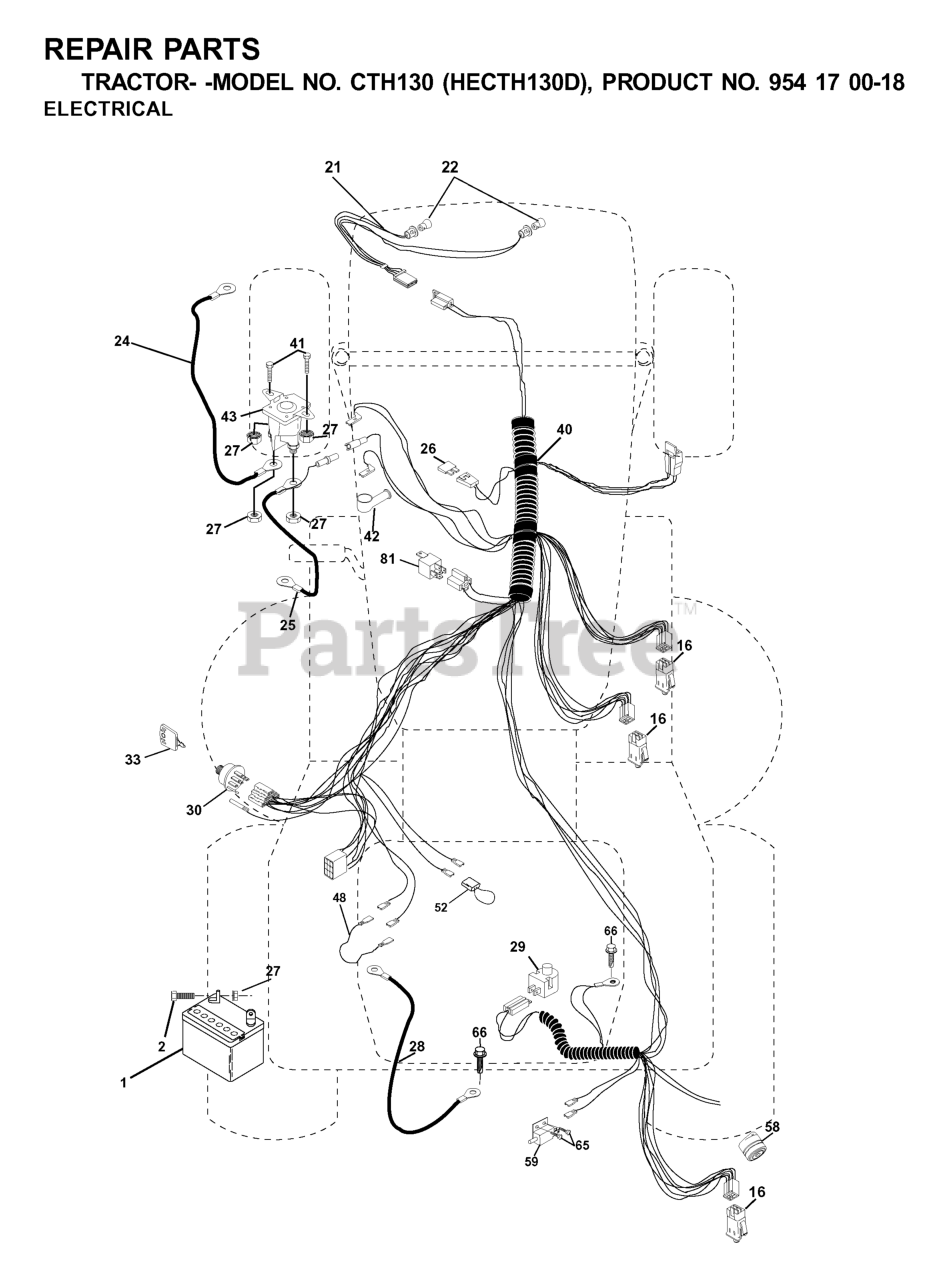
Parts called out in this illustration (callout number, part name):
1	BATTERY 12 VOLT 25 AMP
2	BOLT.HEX.1/4.X.3/4.DICHROMATE
16	SWITCH INTERLOCK
24	BATTERY CABLE GT
25	CABLE BATTERY
26	FUSE 20AMP
27	NUT
28	CABLE GROUND
29	PLUNGER SWITCH (COLOR:OLIVE)
30	IGNITION SWITCH
33	KEY MLD GEN DELTA
40	Harness Ign Crd Noram
41	BOLT
42	TERMINAL COVER
43	REPL BY 532 1461-54
48	ADAPTER.AMMETER
52	WIRE PROTECTION LOOP
58	BUZZER
65	Screw, Hex Wsh. Tap #10-16 x 1/2
81	RELAY.ASSY.T
